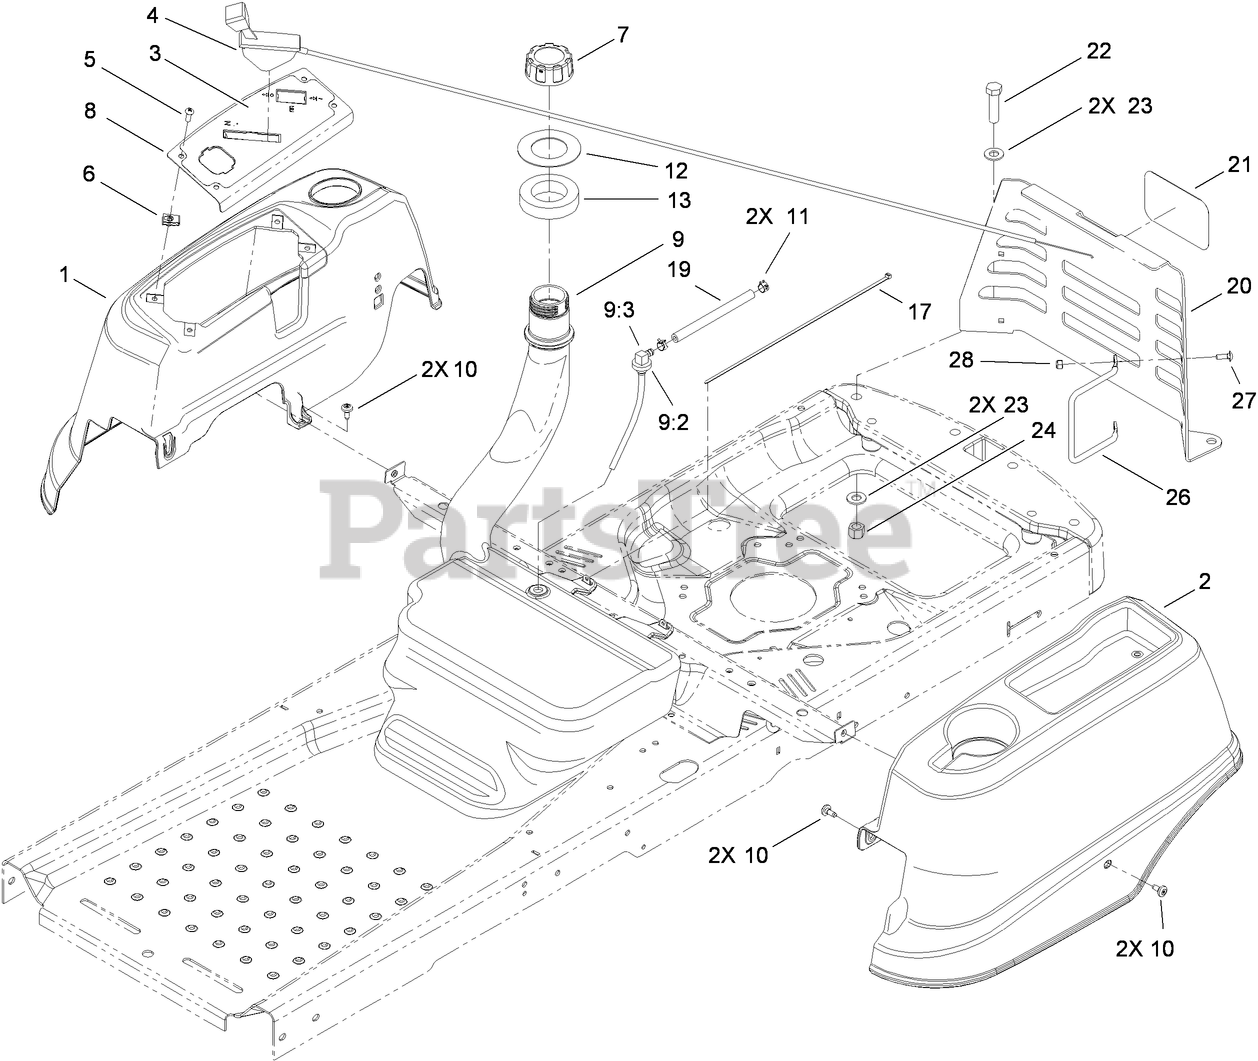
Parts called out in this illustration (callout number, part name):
1	POD-RH
2	POD-LH
3	DECAL-PANEL, CONTROL
4	CABLE-THROTTLE
5	SCREW-PRH
7	CAP-GAS
8	PANEL-CONTROL
9	FUEL TANK ASM
9:2	BUSHING
9:3	FITTING-90 DEGREE
11	CLAMP-HOSE
12	WASHER-RUBBER
13	SEAL-FOAM
17	TIE-CABLE
19	HOSE-FUEL
20	SUPPORT-COVER, REAR
22	SCREW-HH
23	WASHER-FLAT
24	NUT-LOCK, NI
26	GUARD-MUFFLER
27	BOLT-CARR
28	NUT-LOCK, NI
